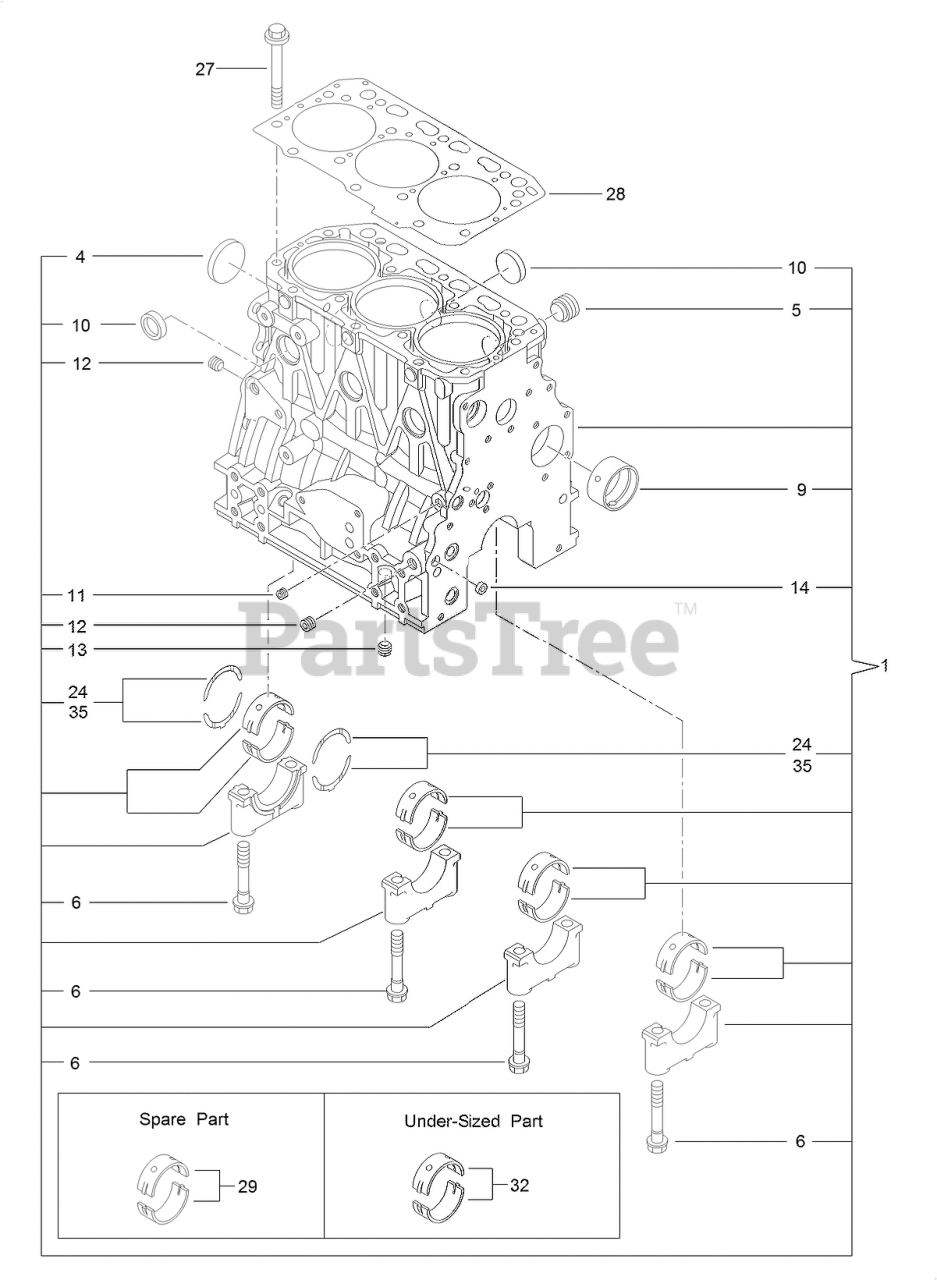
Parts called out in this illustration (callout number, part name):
1	CYLINDER BLOCK ASM
9	BUSHING
24	METAL-THRUST
28	HEAD GASKET ASM
29	METAL-MAIN
32	METAL-MAIN (0.25)
35	METAL-THRUST (0.25)
